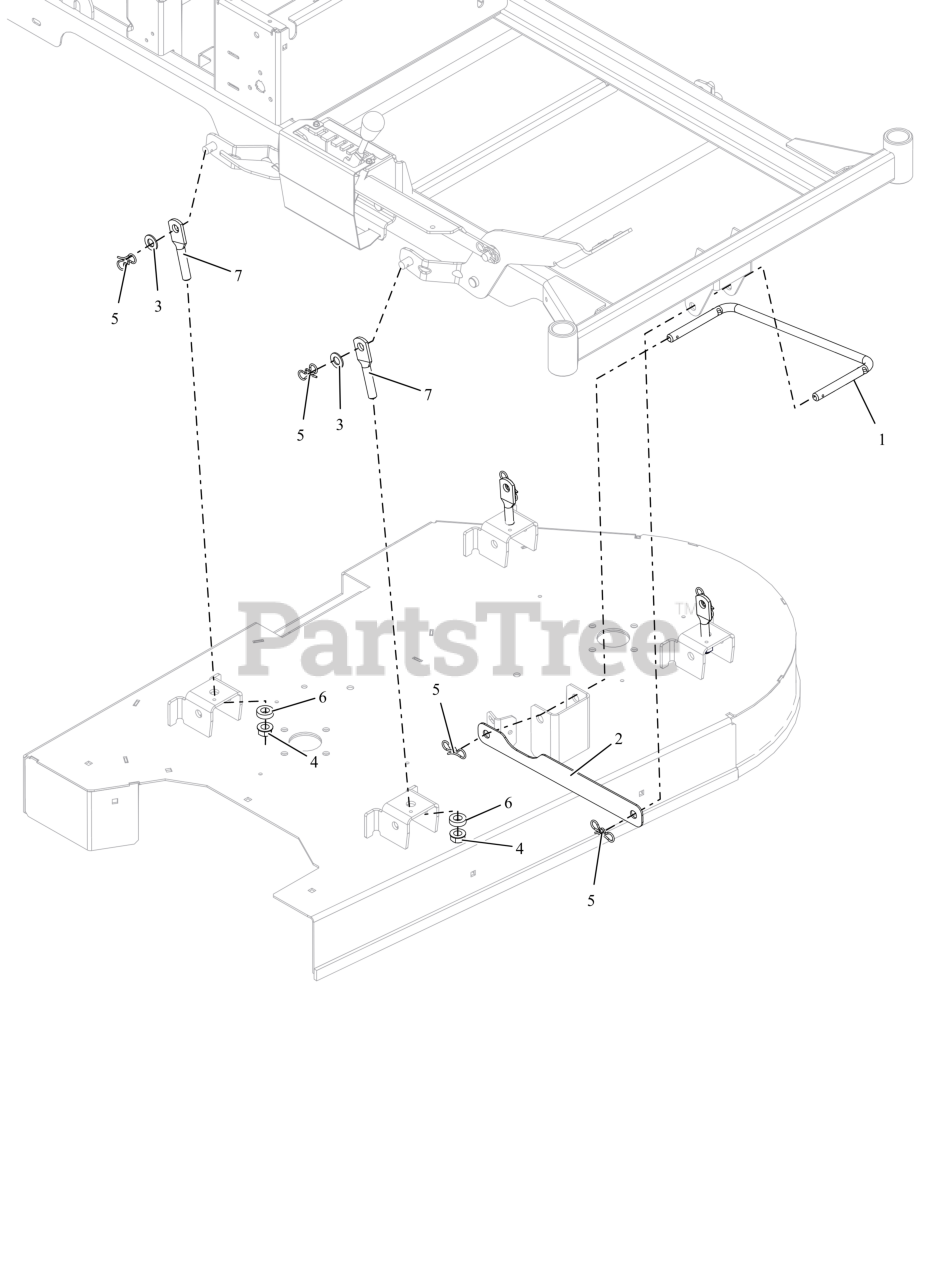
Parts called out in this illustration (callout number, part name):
1	WIREFORM- DRAG LINK
2	STRAP- DRAG LINK
3	WSHR-FL-NYL .518X1.000X.080
4	NUT-LK-CTR-FLG .500-13 GG ZCC
5	PIN, BOWTIE .091X1.875 ZCC
6	WSHR, RUBBER
7	LINK, DECK (HOLE-SHORT)
